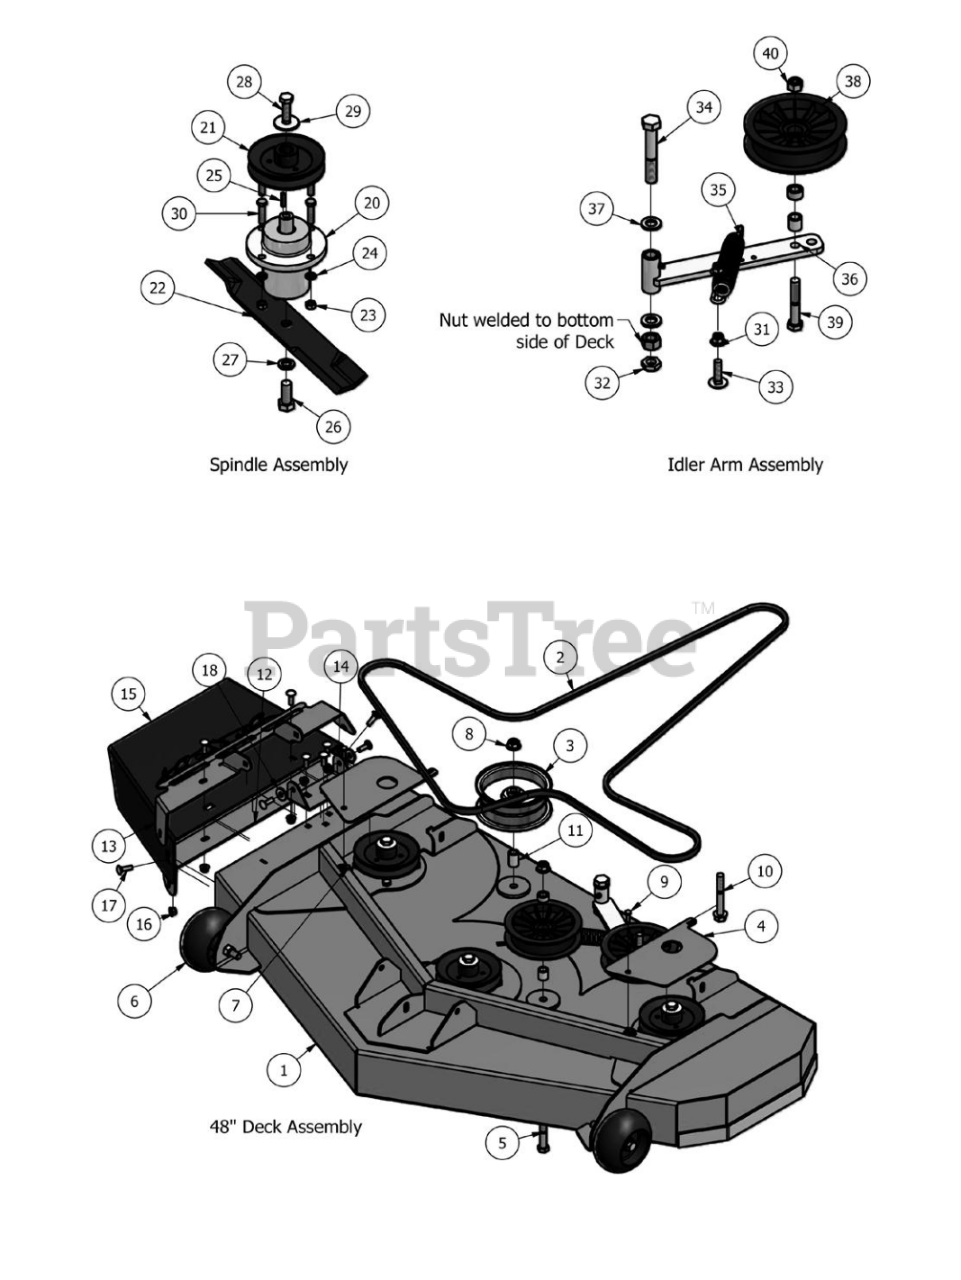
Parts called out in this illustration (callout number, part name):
1	Mz 48" Deck
2	B128 Deck Belt
3	5 3/4" Deck Idler Pulley
4	MZ Pulley Cover
5	1/2 x 2-1/2 Hex Bolt
6	Anti-Scalp Rollers
7	1/4-20 Cage Nut
8	1/2-13 Nylon Insert Flangenut Zinc Orange Nylon
9	1/4-20 x 3/4 Grade 5 Hex bolts Zinc
10	1/2 x 3-1/2 Flange Bolt - Grade 8
11	1-1/8 Spacer
12	MZ Discharge Chute Bracket (Bottom)
13	MZ Discharge Chute Bracket (Top)
14	MZ Discharge Chute Hanger
15	Discharge Chute MZ
16	5/16-18 Nylon Insert Flange Nut Zinc Orange Nylon
17	5/16-18 x 1 Carriage Bolts Zinc
18	.360ID Plastic Washer
19	Anti-Scalp Roller Assembly
20	Spindle and Pulley Assembly MZ Model
21	MZ Deck Pulley
22	48" High Lift Fuzion Blade MZ
23	3/8-16 Hex Nuts Zinc
24	3/8 Lockwasher Zinc
25	3/16 x 1 Square Key
26	5/8-11 X 1-1/2 GR 8 Hex Bolts Zinc
27	5/8 Lock Washer Zinc
28	1/2-20 x 1-1/2 Grade 5 Hex Bolt Zinc
29	Spring Blade Cupped Washer
30	3/8-16 x 1-1/2 GR5 Hex Bolt
31	3/8 Nylock Flange Nut
32	5/8-11 Nylon Insert Jam Locknut Zinc
33	3/8 x 1-1/2 Carriage Bolt
34	5/8-11 X 4 GR 5 Hex Bolts Zinc
35	Deck Idler Spring MZ
36	Deck Idler Bracket
37	.630 IDX 1.122 OD X .142 THK Flat Washer Nylon
38	Plastic Idler Pulley (Mini Z Models)
39	1/2 x 2-1/2 Hex Bolt
40	1/2-12 Nylon Locknut Zinc Orange Nylon
